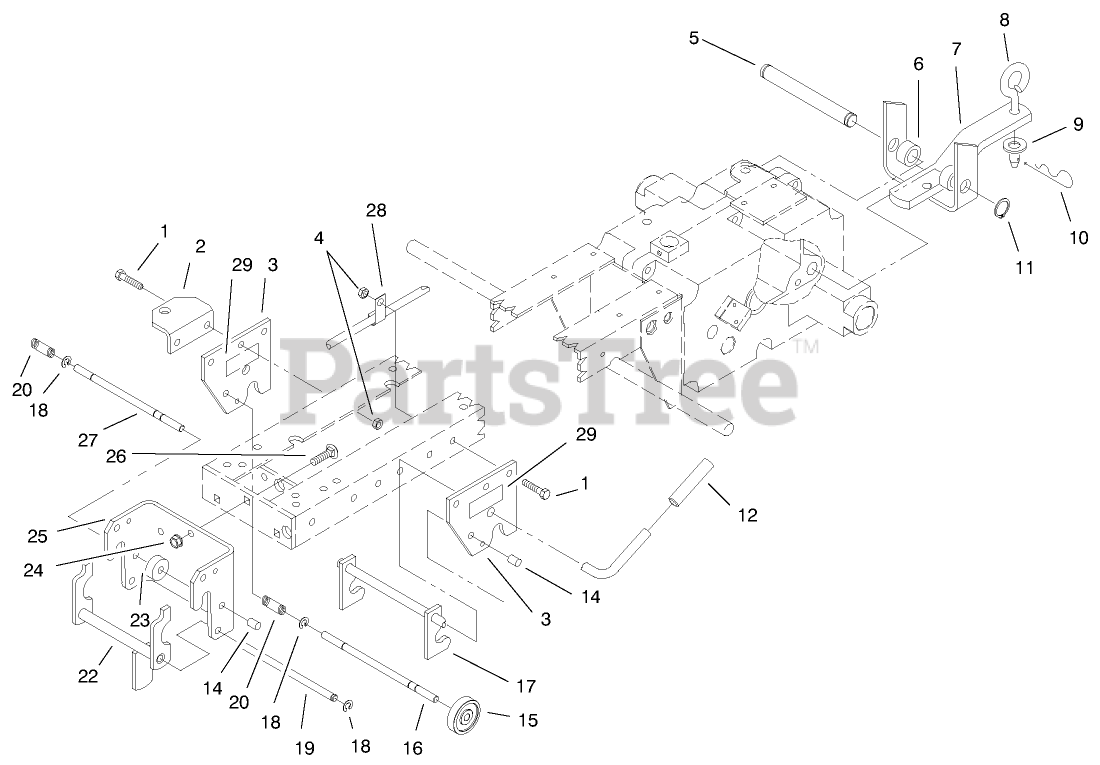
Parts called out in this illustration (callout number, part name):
1	SCREW-HH
2	SUPPORT
3	PLATE-HITCH
4	NUT-HEX
5	PIN-STATIONARY HITCH
6	SPACER
7	HITCH ASM
8	PIN-TOOL
9	WASHER-FLAT
10	PIN-HAIR
11	E-RING
12	GRIP
14	CAP-ROD, PLUNGER
16	ROD-LOCK
17	MID HITCH ASM
18	RING-RETAINING
19	ROD-LATCH PIVOT
20	SPRING
22	LATCH
24	NUT-LOCK, NI
25	HITCH-FRONT
26	BOLT-CARR
27	ROD-LOCK
28	CLIP
29	DECAL-ATTACH A-MATIC
